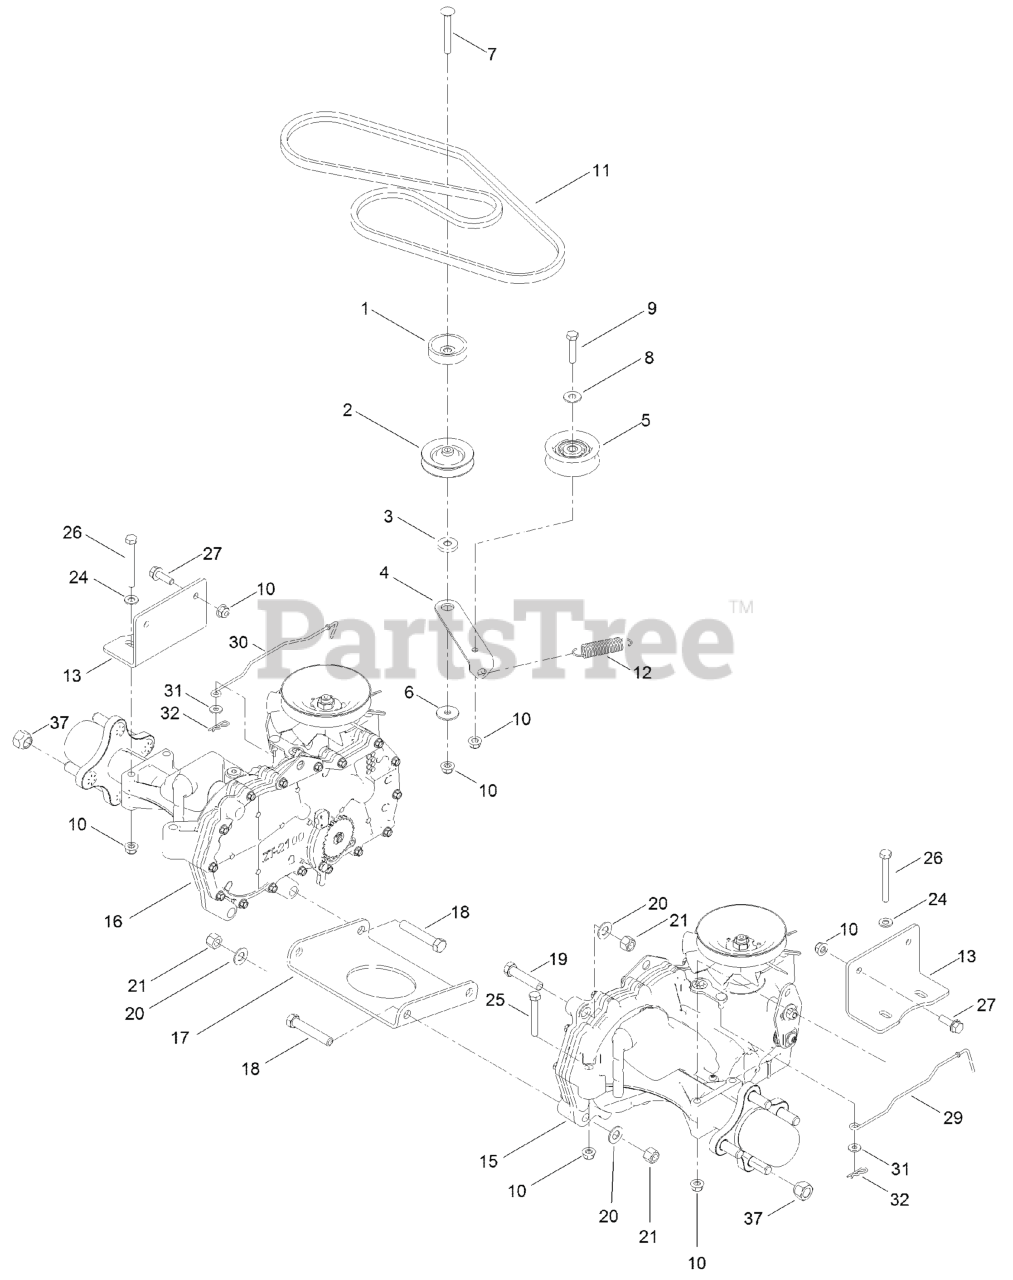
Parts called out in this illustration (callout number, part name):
2	PULLEY-IDLER
3	SPACER-ARM, IDLER
4	Arm-Idler
5	Pulley-Idler, Flat
6	WASHER-PIVOT
7	SCREW-CARR
8	WASHER-FLAT
9	SCREW-HH
10	NUT-HF, NI
11	V-BELT
12	Spring-Return, Pedal
13	MOUNT-HYDRO
15	LH HYDRO TRANSAXLE ASM
16	RH HYDRO TRANSAXLE ASM
17	PLATE-CROSS, HYDRO
18	SCREW-HH
19	SCREW-HH
20	WASHER-FLAT
21	NUT-LOCK, NI
24	WASHER-PLAIN
25	SCREW-HH
26	SCREW-HH
27	SCREW-HHF
29	Rod- Bypass,LH
30	Rod- Bypass,RH
37	NUT-LUG
